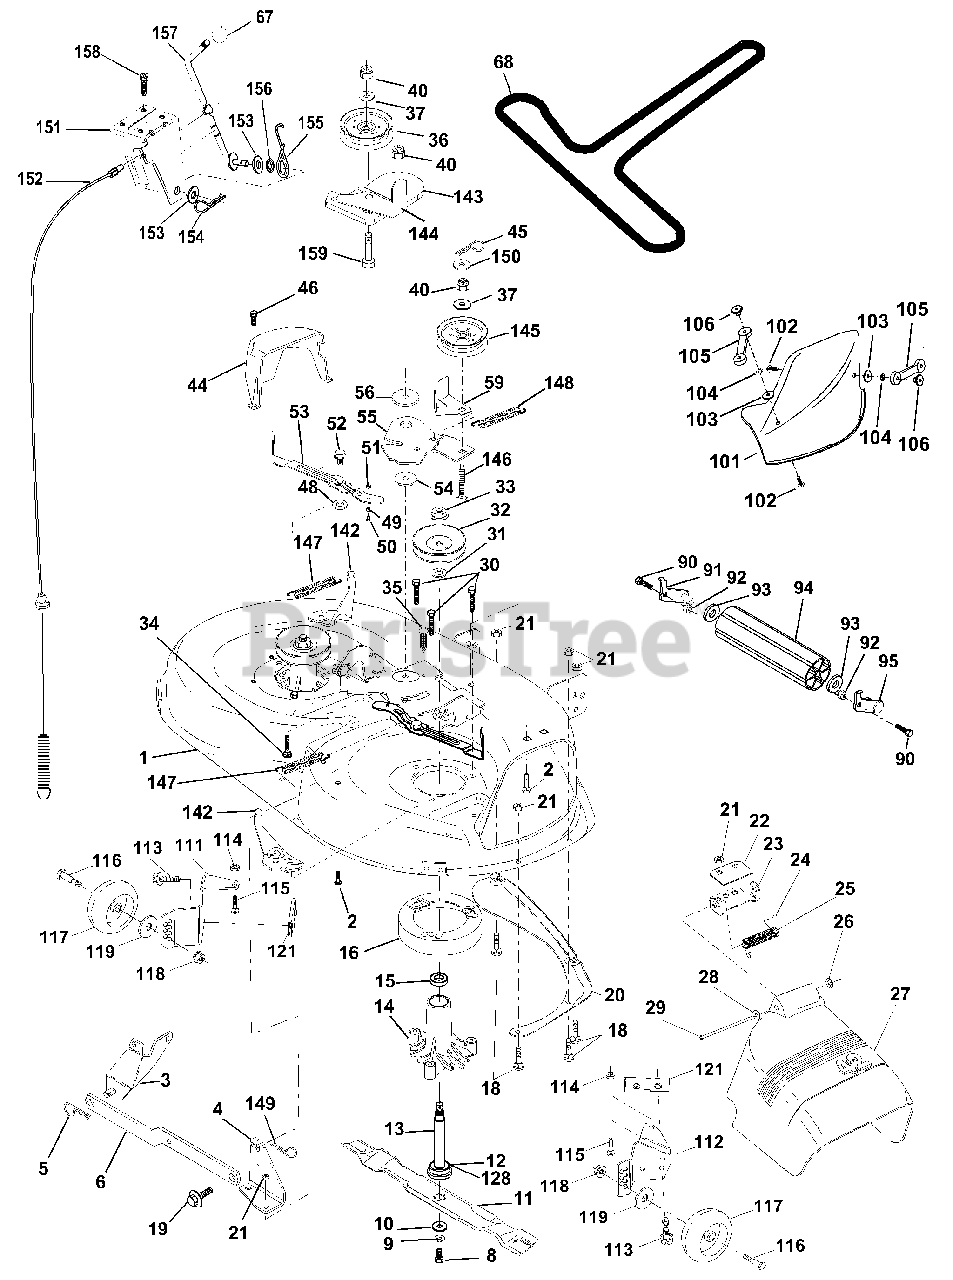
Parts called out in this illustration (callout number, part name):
1	Mower Deck Assembly, 42"
2	Bolt
3	Bracket Asm Fr. Sway Bar 3/42
4	Bracket Asm Deck 42" Sway Bar
5	Retainer Spring
6	Arm, Suspension, Rear
8	Bolt 3/8-24 x 25 Grade 8 patched
9	Washer, Lock
10	Washer,Hardened
11	Blade, Mulching 42"
11	Blade Mower 42" Hi-Lift
12	Bearing, Ball #6204
13	Shaft Assembly, Mandrel, Vented
14	Housing, Mandrel, Vented
15	Bearing, Ball, Mandrel
16	Stripper, Vented Mower Deck
18	Bolt, Carriage 5/16-18 x 5/8
19	Bolt, Shoulder
20	Baffle, Vortex
21	Nut
22	Stiffener Bracket
23	Bracket, Deflector Mower 42"
24	Cap, Sleeve 80 x 112 Blk Mower
25	Spring, Torsion, Deflector 2 52
26	Nut, Push Phos & Oil
27	Shield, Deflector 42" Blk
28	Washer 11/32 x 5/8 x 16 Gauge
29	Rod, Hinge 42" 6 75 W/G
30	Screw Thdrol Washer Head
31	Washer, Spacer Mower Vented
32	Pulley, Mandrel
33	Nut, Toplock 9/16
34	Bolt
35	Fastener, Christmas Tree
36	Pulley, Idler, Flat
37	Washer 13/32 x 13/16 x 16 Gauge
40	Nut
44	Guard, Mandrel, LH
45	Retainer
46	Screw, Thdrol 1/4-20 x 5/8 T
48	Washer,Hardened
49	Roller Assembly, Cam Follower
50	Bolt, Shoulder #10-24 Grade 5
51	Locknut
52	Bolt, Shoulder 5/16-18 UNC
53	Arm Assembly, Pad, Brake
54	Washer, Hardened
55	Arm, Idler
56	Spacer, Retainer
59	Guard TUV Idler
67	Knob
68	V-Belt, 42" Mower
90	Bolt Fin Hex 3/8-16 Unc x 1
91	Bracket Asm. Noseroller LH
92	Nut, Lock, Hex W/Ins 3/8-16 UNC
93	Washer 17/32 x 7/8 x 16 Ga.
94	Roller, Nose
95	Bracket Asm. Noseroller RH
101	Mulcher Cover
102	Screw
103	Washer, Flat
104	Washer, Lock
105	Latch Assembly
106	Nut, Weld
111	Bracket, Gauge, Wheel LH
112	Bracket, Gauge, Wheel RH
113	Screw 5/16 - 18 x 3/4
114	Nut, Keps 5/16 - 18 UNC
115	Bolt, Carriage 5/16-18 x 1/2
116	Bolt, Shoulder
117	Wheel, Gauge
118	Nut Centerlock 3/8-16
119	Washer 3/8 x 7/8 x 14 Ga.
121	Bracket, Extruded
128	Washer, Felt
129	Washer 13/32 x 13/16 x 12 Ga.
130	Bolt Fin Hex 3/8-16 UNC x 1 Gr.
131	Bolt Rdhd Sqnk 3/8-16 UNC x 1
142	Arm Spring Brake Mower
143	Bracket Arm Idler 42"
144	Keeper Belt 42" Clutch Cable
145	Pulley Idler Flat
146	Bolt Carriage Idler
147	Spring Extension
148	Spring Return Idler
149	Retainer Spring Yellow
150	Washer 9/32 x 3/4 x 16 Ga.
151	Bracket Clutch Cable
152	Clutch Cable 42"
153	Washer Flat 3/8" Type B
154	Spring Retainer
155	Spring Retention LVR CLTCH CAB
156	Spacer Clutch Cable
157	Rod Clutch Cable 3/8"
158	Screw Hex Thd Cut 1/4-20 x 5/8
159	Bolt Rdhd Sqn 3/8-16 UNC x 1-3/4
